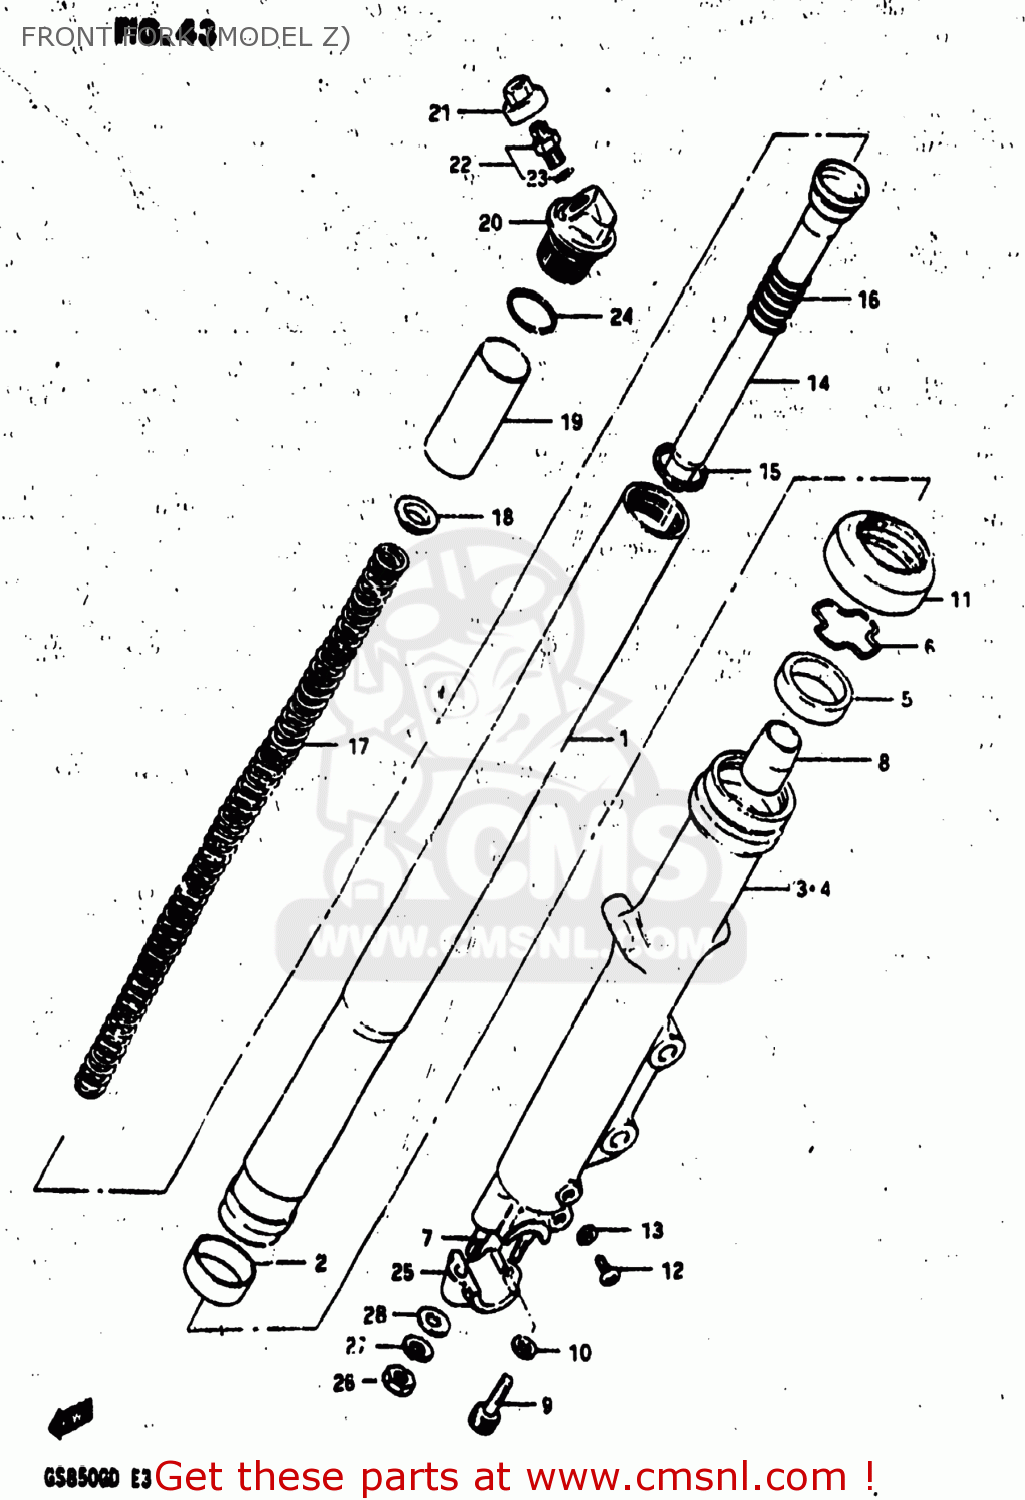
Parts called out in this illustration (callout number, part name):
0	DAMPER ASSEMBLY,LEFT
1	TUBE,FORK,INNER
2	PISTON
3	TUBE,FORK,OUTER,RIGHT
4	TUBE,FORK,LEFT,OUTER
5	OIL SEAL,FRONT FORK
6	RING,STOPPER
7	STUD BOLT
8	PIECE,OIL LOCK
9	BOLT,FORK CYLINDER(10X25)
10	GASKET (NAS)
11	SEAL,DUST
12	SCREW
13	GASKET,DRAIN,PLUG (NAS)
14	CYLINDER,FRONT FORK
15	RING,PISTON
16	SPRING,REBOUND
17	SPRING,FRONT FORK
18	GUIDE,FRONT FORK SPRING C
19	SPACER,SPRING
20	CAP,FORK INNER TUBE
21	CAP,VALVE
22	VALVE
23	O RING
24	O RING
25	HOLDER,AXLE
26	NUT (8MM)
27	LOCK WASHER
28	WASHER
